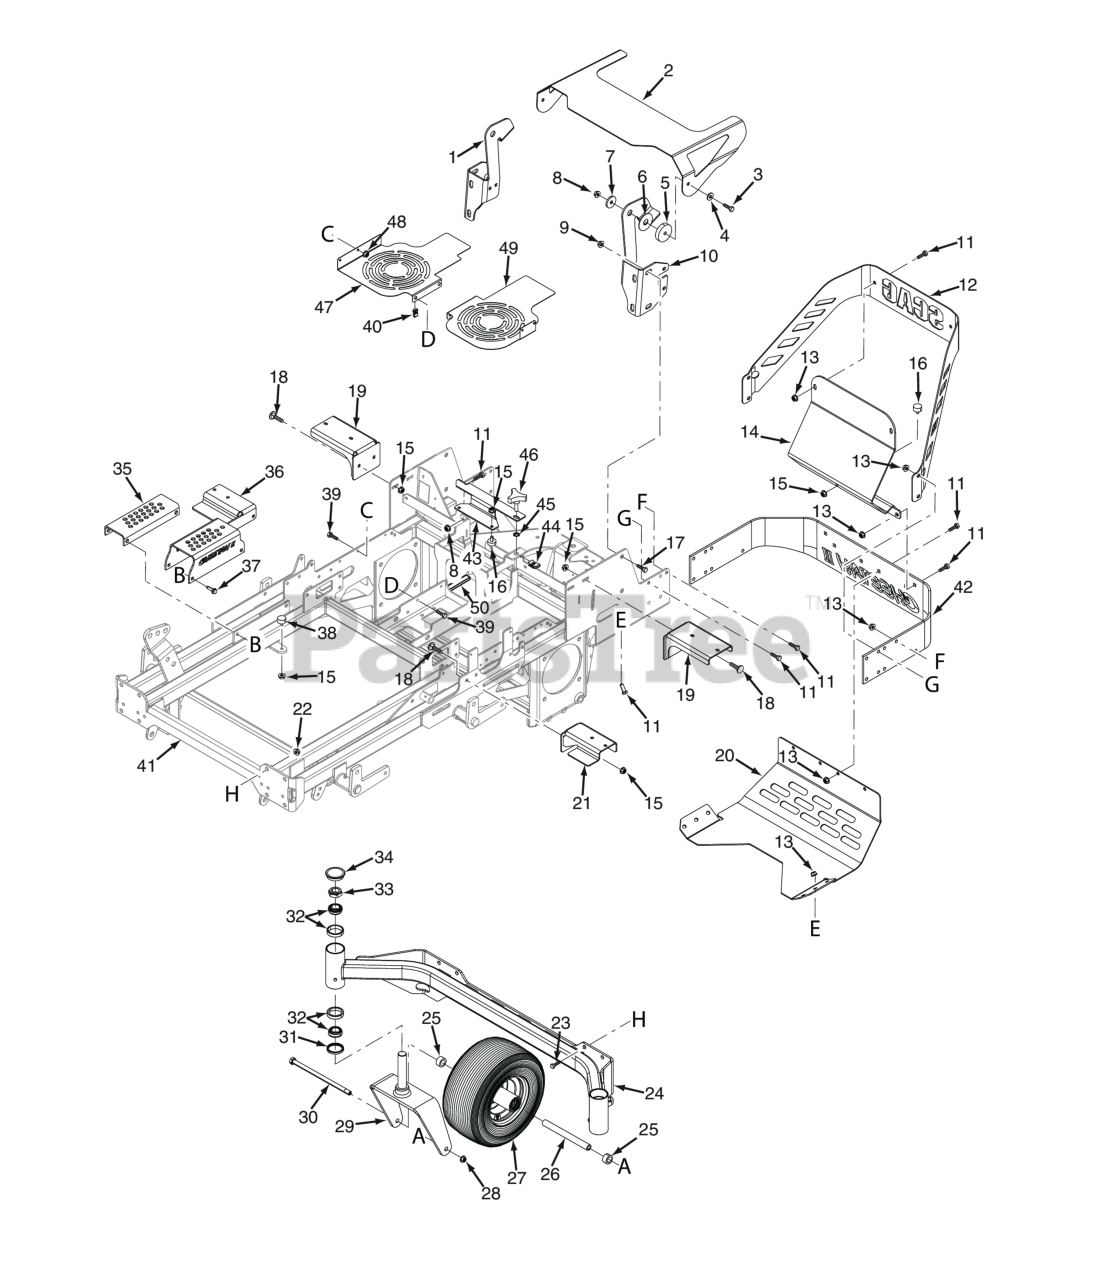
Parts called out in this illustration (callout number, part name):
1	ROPS Mount, RH, 29CV-EFI
2	Hood, SCZII
3	Bolt, Hex Head 3/8-16 x 1-3/4" (Kohler EFI)
4	Flatwasher, 3/8" Special (.391 x .938 x .105)
5	Spacer, Hood
6	Disc, Anti-Friction
7	Flatwasher, 3/8-.406 x 1-1-1/2 x 7 Gauge
8	HEX NUT, ELASTIC STOP LOCK, 3/8-16
9	Nut, Elastic Stop 1/2-13, (STT-52 & STTII-52)
10	ROPS Mount, LH, 29CV-EFI
11	Bolt, Hex Head, 3/8-16 x 1 Gr. 5
12	Engine Cover, Sides
13	NUT, 3/8-16 SERRATED FLANGE HEX HEAD
14	Engine Cover, Rear
15	Nut, Serrated Flange 5/16-18 (Right Front Engine Mounting, Briggs and Kohler Only)
16	Bumper, Rubber 5/16-18 x 5/8"
17	Bolt, Hex Head 1/2-13 x 1-1/4"
18	Bolt, 5/16-18 x .75 RHSN Carriage
19	Mounting Bracket, Fuel Tank Rear
20	Skid Plate, Rear
21	Mounting Bracket, Fuel Tank Front
22	Nut, 7/16-14 Flange Elastic Stop
23	BOLT, HEX HEAD, 7/16-14 X 1-1/4
24	Caster Support Weldment, 61V
24	Caster Support Weldment, 72V
25	Spacer, Caster Wheel
26	Sleeve, Caster Wheel (61V, 72A/VS)
27	Wheel Assy, 61V, 72V (Incl. 20, 54, 55)
27	Bearing, Tapered Roller
27	Roller Bearing, Short
28	HEX LOCKNUT, ELASTIC STOP, 1/2-13
29	Yoke Weldment
30	Bolt, Hex Head 1/2-13 x 9-1/2" (61V & 72A/VS)
31	Seal, 2.00" O.D. x 1.625" Bore
32	BEARING & CUP, TAPERED SPINDLE
33	Nut, Hex Elastic Stop 1.0"-14
34	Cap, Grease
35	Adjustment Bracket, Lower Cut Height
36	Bracket, Upper Cutting Height
37	Bolt, Hex Wshr Head 5/16-18 x 1-1/4"
38	Bumper, Rubber
39	Bolt, Serrated Flange Hex Head 1/4 x 20 x 3/4"
40	Bolt, Hex Head 3/8-16 x 1"
41	Frame w/ Decals
42	Bumper, Rear
43	Cover, Battery Box
44	U-Nut, 3/8-16 (short)
45	Nut, Push-On - 3/8" Dia.
46	Knob, w/stud 3/8-16 x 1-1/4"
47	Fan Cover, RH
48	NUT, 1/4-20 SERRATED FLANGE HEX HEAD
49	Fan Cover, LH
50	PAD, BATTERY SUPPORT
